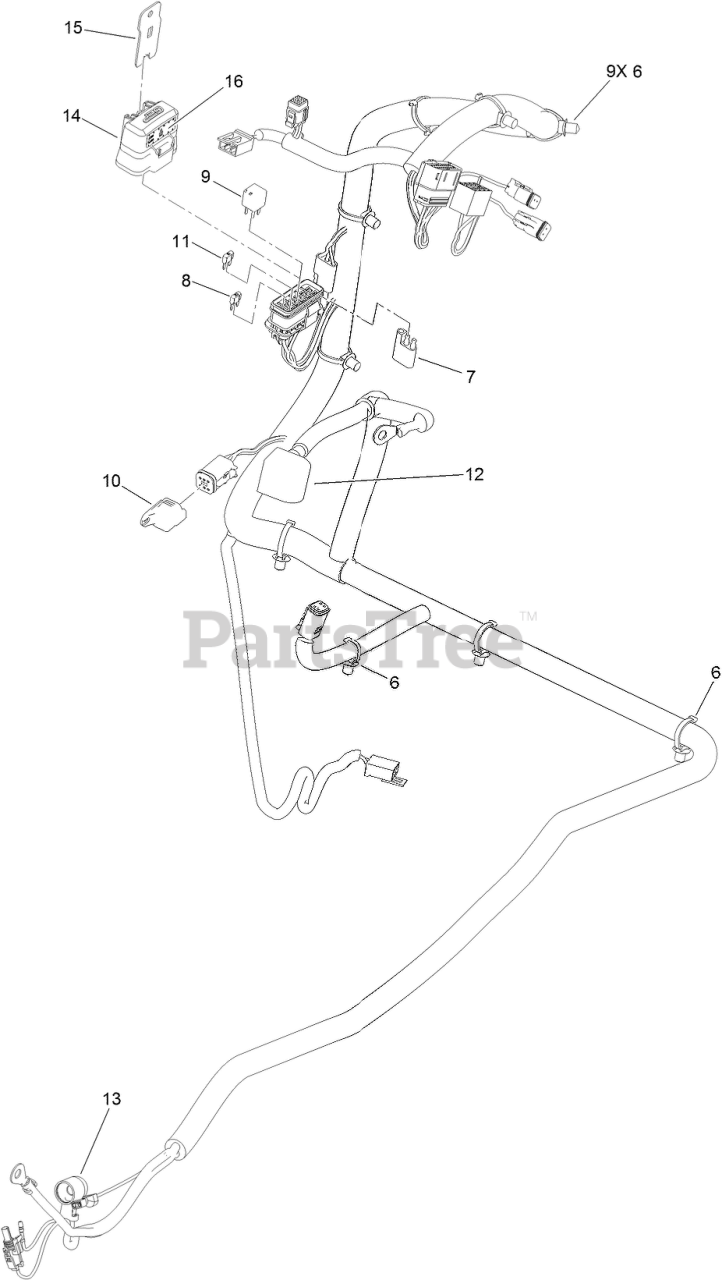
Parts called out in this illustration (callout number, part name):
6	CLIP-TIE
7	Cap-Plug
8	FUSE-MINI BLADE, 20 AMP
9	RELAY-MICRO
10	CAP-PLUG, 6 WAY
11	FUSE-MINI BLADE, 15 AMP
12	INSULATOR-BATTERY
13	INSULATOR-SOLENOID
14	COVER-BLOCK, FUSE
15	CLIP-MOUNTING
16	DECAL-FUSE
